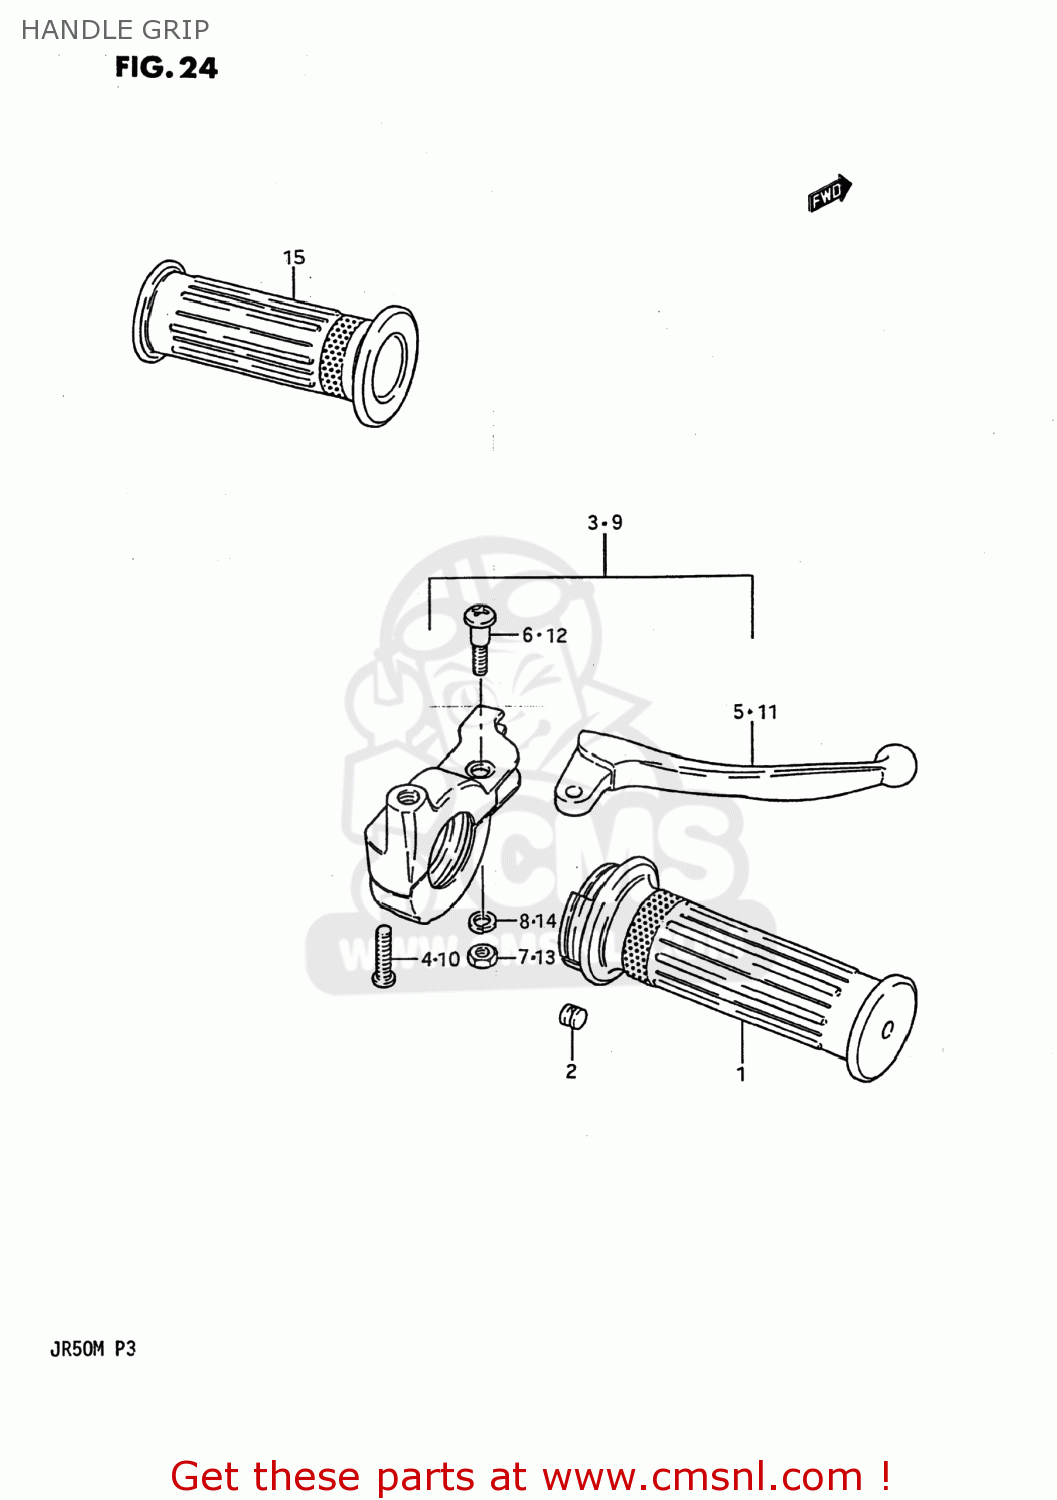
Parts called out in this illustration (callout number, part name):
1	GRIP,THROTTLE
2	PIECE,THROTTLE END
3	LEVER ASSY,BRAKE
4	SCREW
5	LEVER,BRAKE
6	SCREW
7	NUT
8	LOCK WASHER
9	LEVER ASSY,BRAKE
10	SCREW(5X22)
11	LEVER,BRAKE
12	SCREW,BRAKE LEVER PIVOT
13	NUT ,5MM
14	WASHER,LOCK
15	GRIP,L
